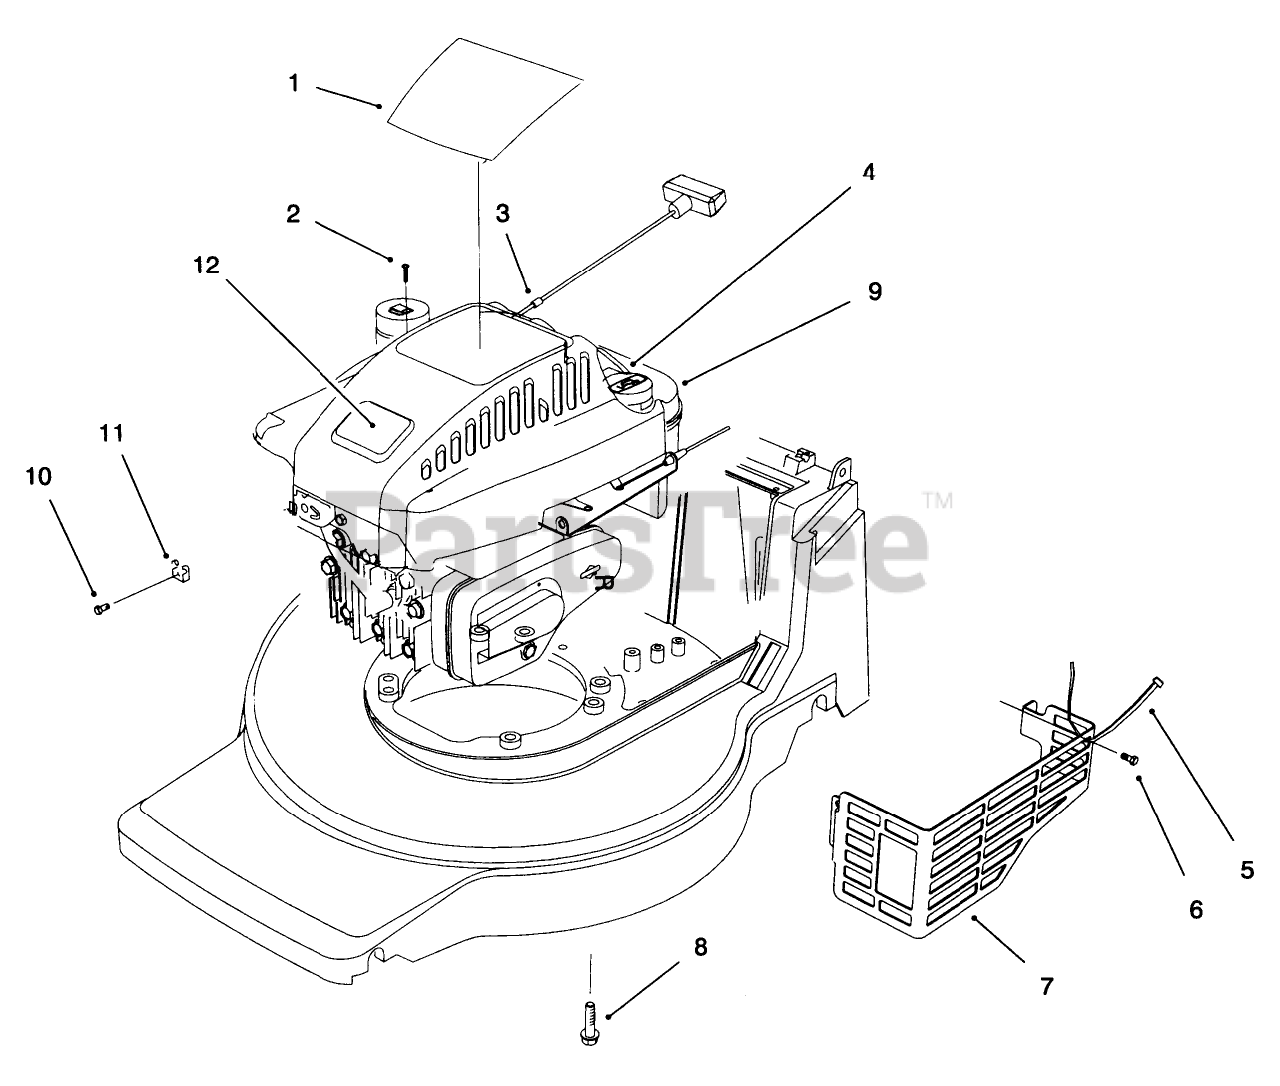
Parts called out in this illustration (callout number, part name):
1	DECAL - RECOIL
2	SCREW-PPH
3	STOP-ROPE
4	SHROUD-ENGINE
5	TIE-CABLE
6	SCREW-HWH
7	SHIELD-MUFFLER
8	SCREW-HWH
9	Engine-B & S Quantum
10	SCREW-CLAMP
11	CLAMP-CASING
12	PLATE-LOGO
